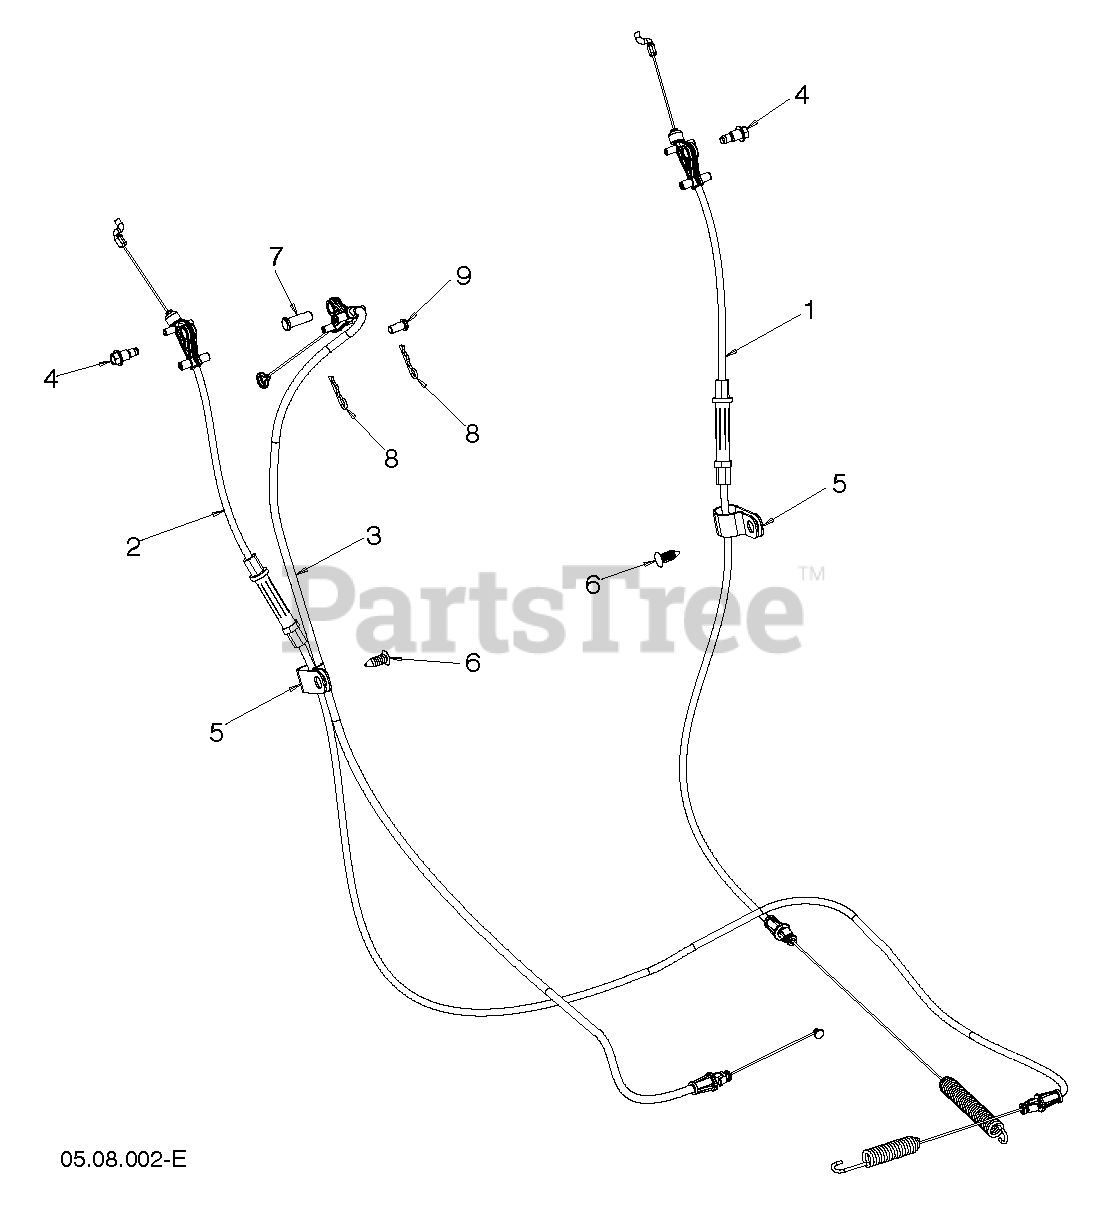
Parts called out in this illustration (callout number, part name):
1	Drive Control Cable, DSST OPP
2	Auger Control Cable, DSST High-Crank
3	Speed Control Cable, DSST OPP
4	Shoulder Bolt, 1/4-20 Trilob
5	CLIP.CABLE.BLK
6	FASTENER.PUSH.O.250X0.783
7	Clevis Pin, 5/16 X .875
8	Hair Pin, .059 X 1.125
9	Clevis Pin, .25 X .31
